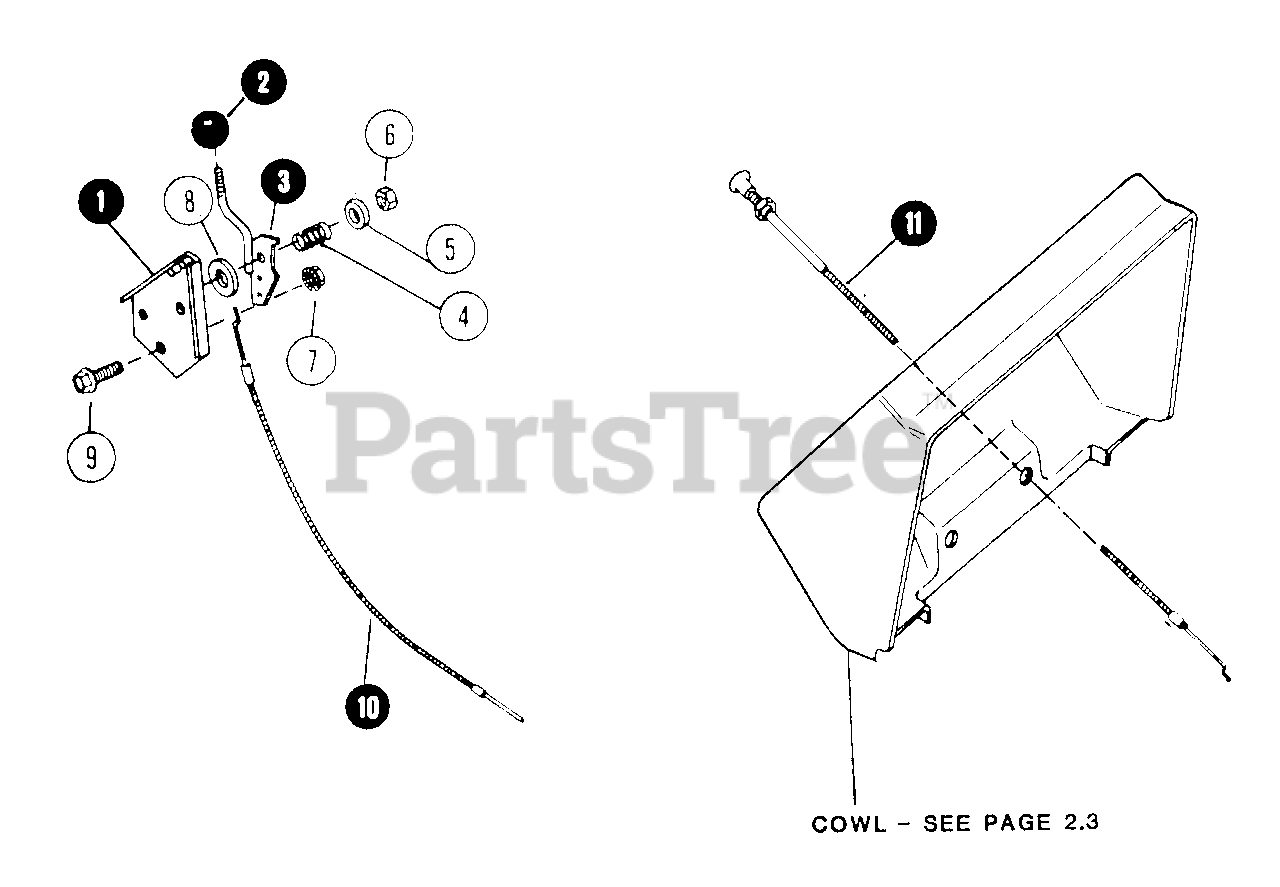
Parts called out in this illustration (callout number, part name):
1	BRACKET, THROTTLE CONTROL
2	KNOB, THROTTLE ARM
3	ARM, THROTTLE CONTROL
4	SPRING, ARM TENSION
5	WASHER, 5/16 FLAT
6	NUT, 5/16C HEX LOCK
7	NUT, 3/8C HEX FLANGE LOCK
8	WASHER, FRICTION
9	BOLT, 3/8C x 3/4 HEX
10	CABLE, THROTTLE CONTROL
11	CABLE, CHOKE CONTROL
